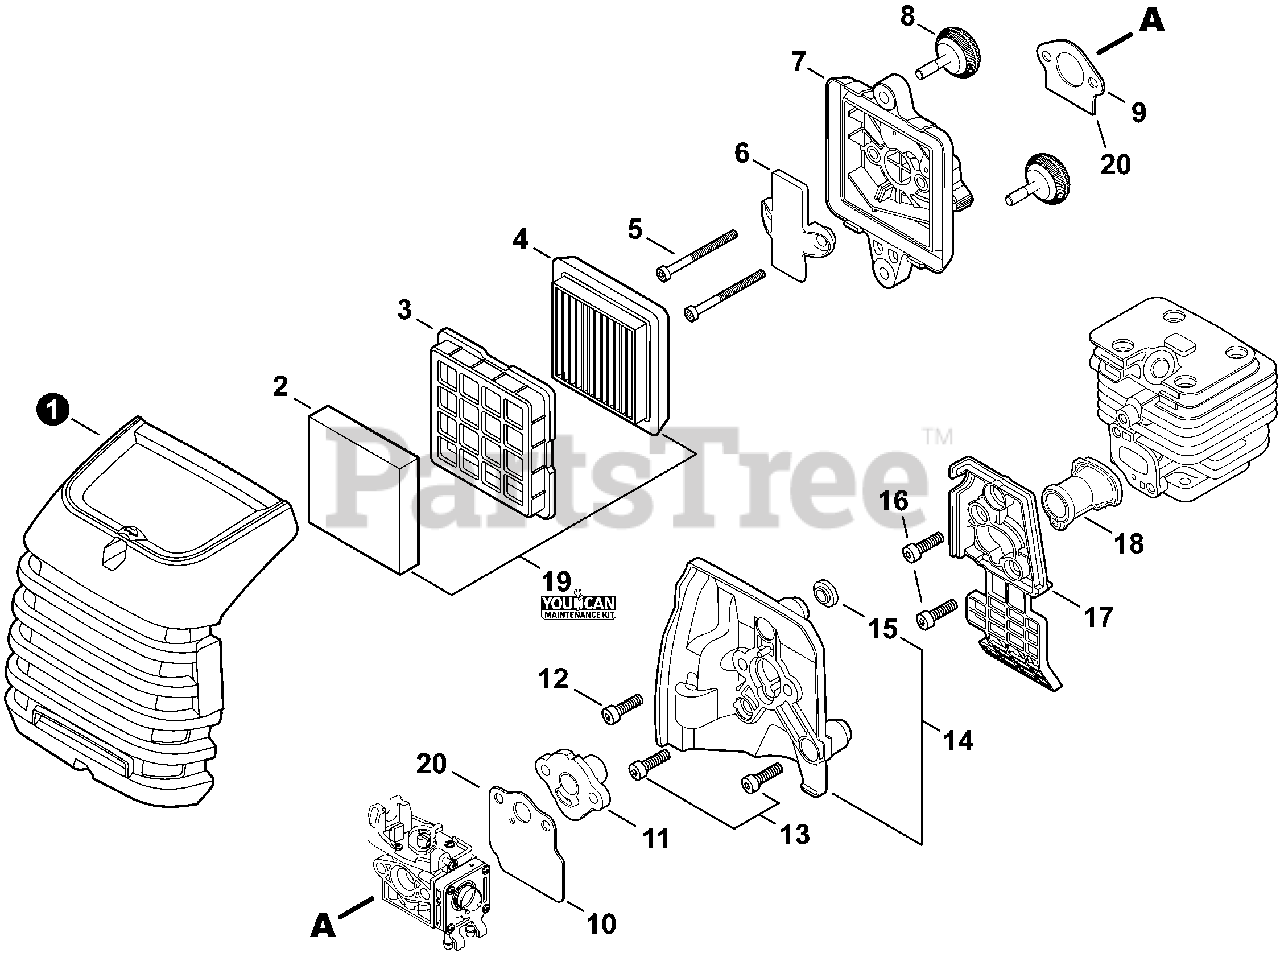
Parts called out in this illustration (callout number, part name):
1	COVER, AIR FILTER
2	PRE-FILTER, FOAM
3	RETAINER, PRE-FILTER
4	FILTER, AIR
5	BOLT, TORX 5×60
6	PLATE, PREVENT
7	CASE, AIR FILTER
8	THUMBSCREW
9	GASKET, INTAKE
10	HEAT SHIELD, INTAKE
11	BOOT, INSULATOR PLATE
12	BOLT, TORX 5×20
13	BOLT, TORX 5×16
14	PLATE, INSULATOR
15	COLLAR 5
16	SCREW 5×16
17	HOLDER, BELLOWS
18	BELLOWS, INTAKE
19	TUNE-UP KIT - YOUCAN™
20	GASKET KIT
